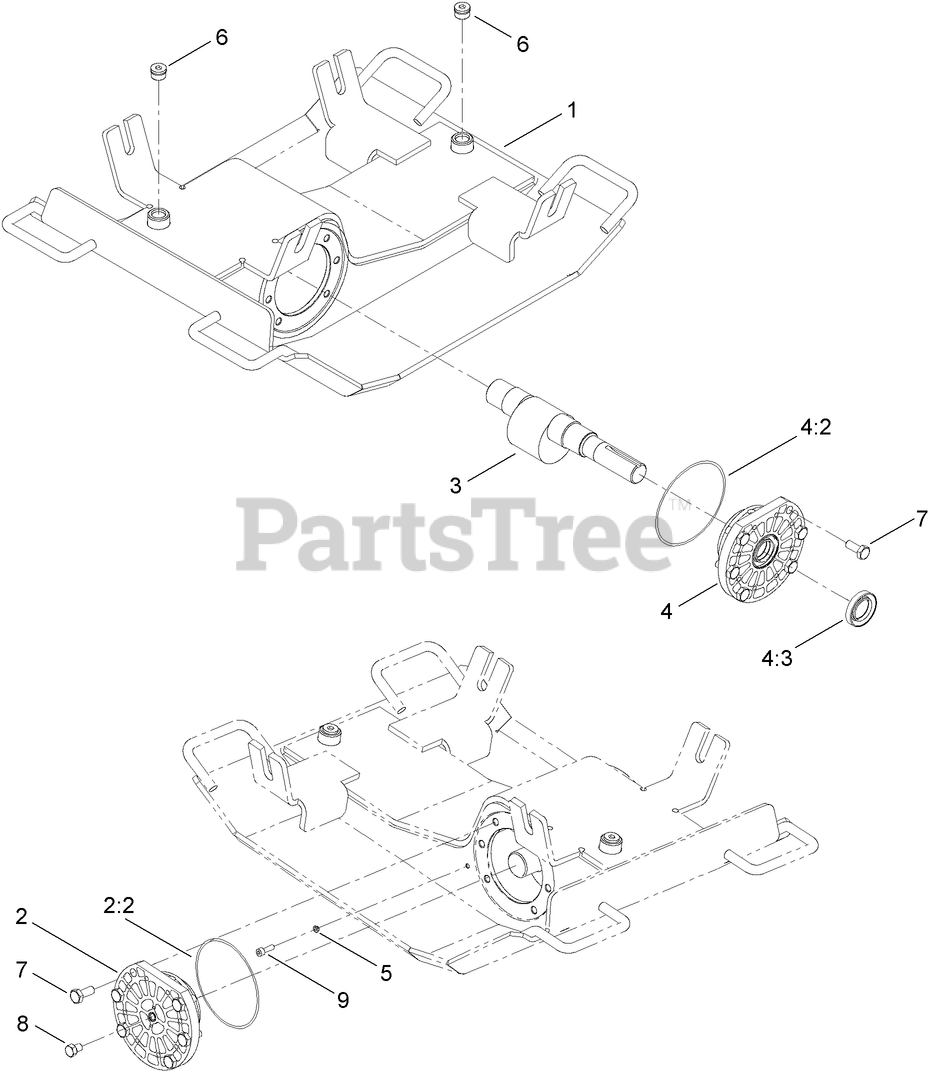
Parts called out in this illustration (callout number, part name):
1	BASE
2	PLATE CAP BEARING ASM (BLIND END)
2:2	O-RING
3	SHAFT-ECCENTRIC
4	PLATE CAP BEARING ASM (SHEAVE END)
4:2	O-RING
4:3	SEAL-SHAFT
5	WASHER-SEALING, NYLTITE
6	FITTING-HYD
7	SCREW-HH
8	SCREW-HH
9	SCREW-HSH
